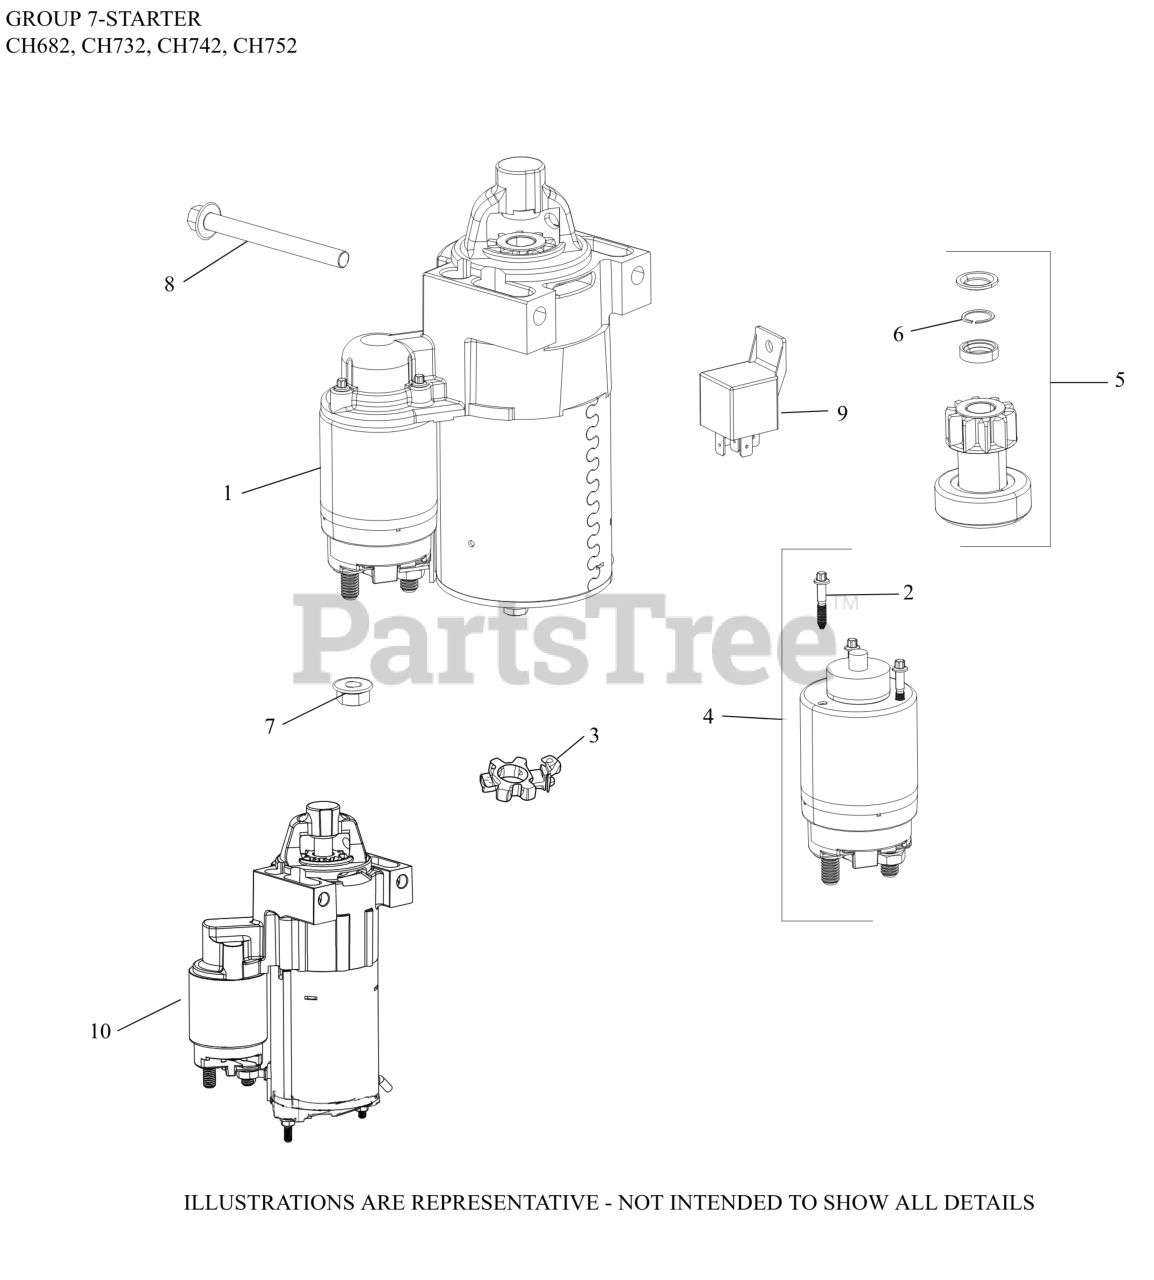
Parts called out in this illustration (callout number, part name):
1	STARTER, SOLENOID SHIFT-(#2509824S)
7	NUT, FLG M8X1.25
8	SCREW, FLG M8X1.25X80
